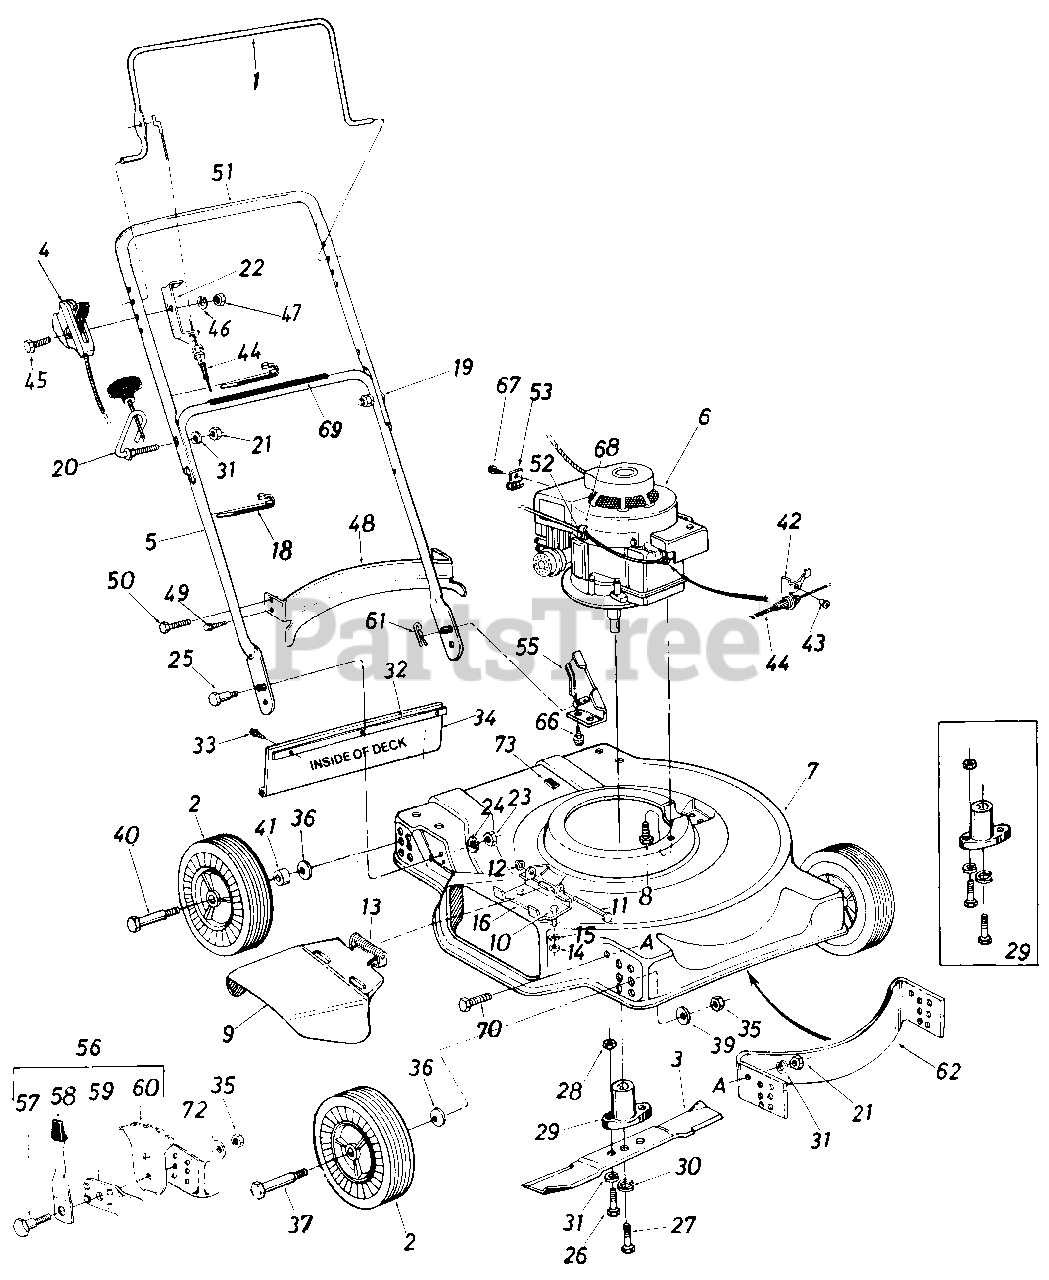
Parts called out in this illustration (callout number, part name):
1	Control Handle-R.H.
2	Plastic Rim (7 x 1.5)
3	22" Blade
4	Throttle Control Ass'y.-41"
5	Lower Handle (Chrome)
6	Engine
7	22" Deck Ass'y
8	Hex Wash. Hd. TT-Tap Scr. 3/8-16 x 1.00" Lg.
9	Chute Deflector Ass'y.
10	Hex Bolt 1/4-20 x .50" Lg.
11	Hinge Pin 1/4" Dia. x 3.88 Lg.
12	Push Cap .25" Rod
13	Torsion Spring
14	Hex Nut 1/4-20 Thd.
15	L-Wash. 1/4" I.D.
16	Deflector Hinge Plate
18	Cable Tie
19	Curved Carriage Bolt 5/16-18 x 1.38" Lg.
20	Rope Guide Bolt
21	Hex Nut 5/16-18 Thd.
22	Cable Mtg. Brkt.
23	Hex Ins. L-Nut 5/16-18 Thd.
24	Bell-Wash. .345" I.D. x .88"
25	Shld. Bolt .437" Dia. x .268
26	Hex Bolt 5/16-24 x 1.00" Lg. (Grade 5)
27	Hex Bolt 3/8-24 x 2.25" Lg. (Grade 5)
28	Hex Nut 5/16-24 Thd.*
29	Blade Adapter Kit
30	L-Wash. 3/8" I.D.-H.D.
31	L-Wash. 5/16" I.D.
32	Retainer Strip
33	Hex Wash. Hd. AB-Tap Scr. 1/4" x.62" Lg.
34	Rear Flap Ass'y.
35	Hex Nut 3/8-16 Thd.
36	Bell-Wash. .400" I.D. x .88"
37	Front Axle Bolt
39	Bell-Wash. .39" I.D. x 1.13"
40	Rear Axle Bolt
41	Spacer .511 I.D. x .70" O.D.
42	Cable Bracket
43	Pop Rivet .156" Dia. x .379
44	49" Control Cable-Blue
45	Hex Bolt 1/4-28 x 1.75" Lg.
46	Spring Wash. .270" I.D. x .57" O.D.
47	Hex Nut 1/4-28 Thd.
48	Rear Baffle
49	Truss Mach. B-Tap Scr. #10 x .50" Lg.
50	Hex Bolt 5/16-18 x .75" Lg.
51	Upper Handle (Chrome)
52	Hex "B" Tap Scr. #10 x .38"
53	Casing Clamp
55	Handle Mount Brkt. Ass'y.-L.H.
56	Height Adjuster Ass'y. Comp.-R.H.
57	Shoulder Bolt .500" Dia. x .357
58	Spring Lever Ass'y. w/Knob
59	Pivot Bar
60	Index Plate
61	Hairpin Cotter
62	Front Baffle
66	Hex Wash. Hd. Self-Tap Scr. 5/16-18 x .50" Lg.
67	Hex Wash. Hd. AB-Tap Scr. #8 x .38" Lg.
68	Cable Clip
69	Instruction Label-Handle
70	Hex Bolt 3/8-16 x .75" Lg.
72	Belleville Wash. .39 I.D. x 1.4 O.D.
73	Plastic Plug
